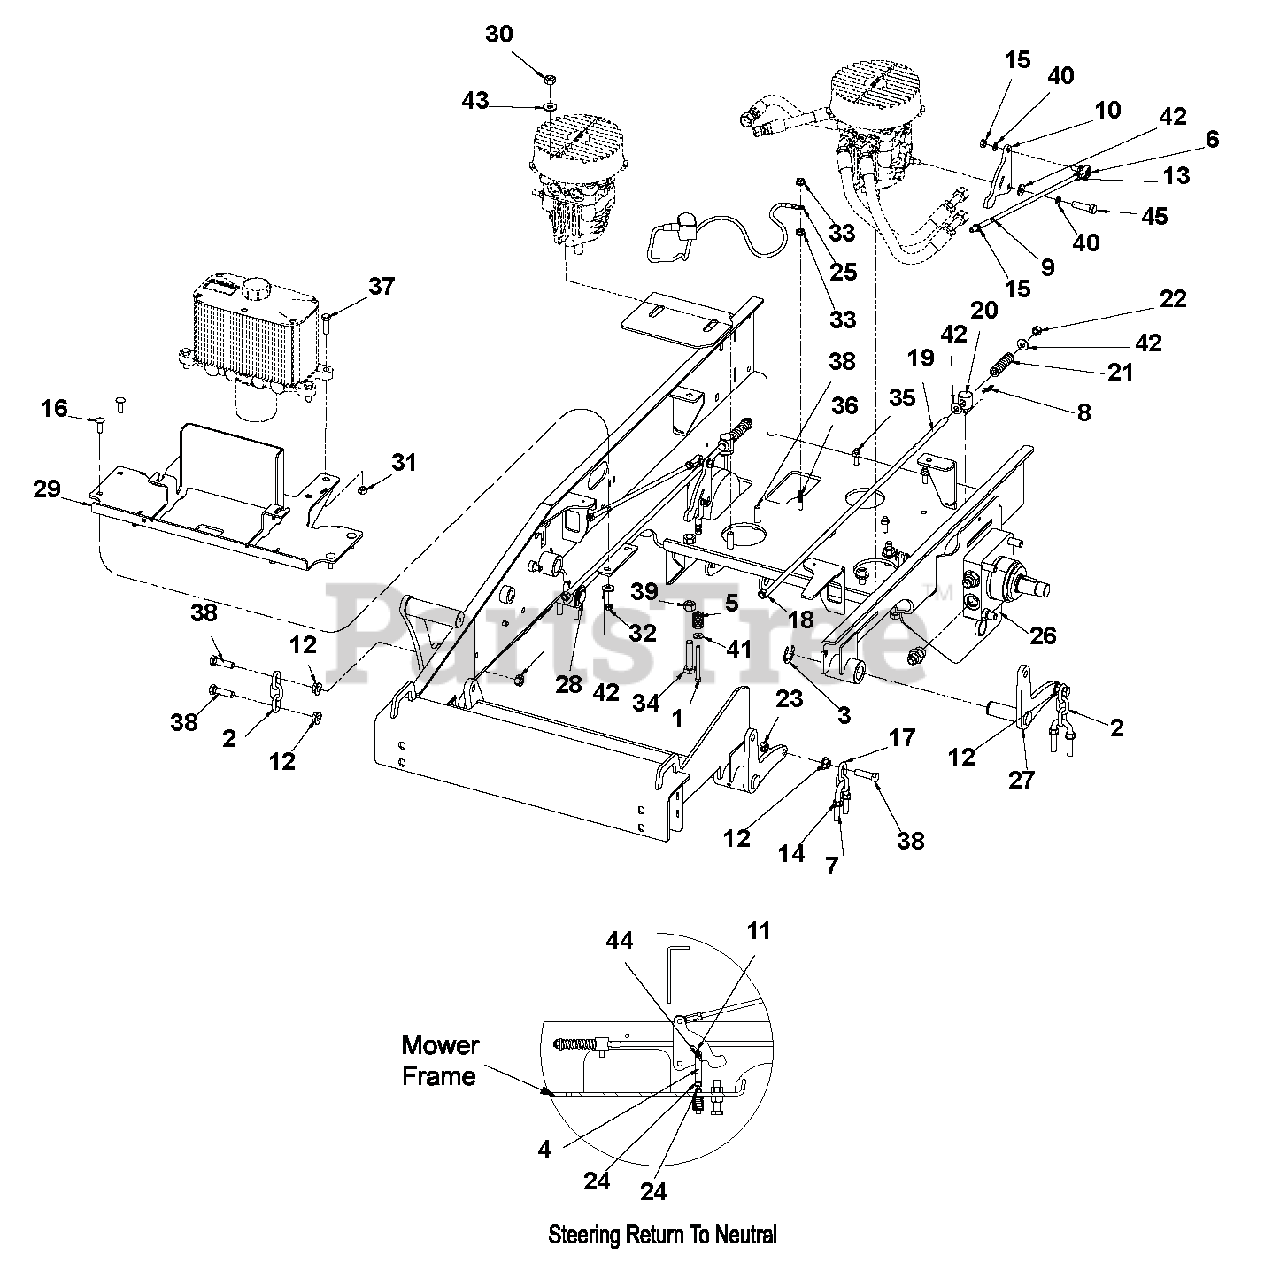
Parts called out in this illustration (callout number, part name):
1	BOLT, 1/4-20X2.75 SOC 8 Y
2	CHAIN, 1/4 X 3 LINKS Y
3	E-RING, 1.00 X .050 Y
4	YOKE, 1/4-20 RH ADJUSTABLE
5	SPRING, COM .784X.092X1.50
6	BALL JOINT, 5/16 FMAL W/STD
7	U-BOLT, RD 1.00X2.50X3/8-16 Y
8	RING, RUE .375 X .054 X 1.254
9	ROD, PUMP CONTROL HORNET
10	PLATE, PUMP CONTROL ARM
11	RING, RUE .250 X .041 X .844
12	LOCKNUT, 7/16-14 WHIZ Y
13	NUT, 5/16-24 HEX GR5 LH Y
14	NUT-SPIRALOCK-FLG .50-13 PLN
15	NUT-HEX .312-24 YWZC
16	@BLT-RDHDSQNK .31-18X1.00 G5YZ
17	CHAIN, 2 LINKS 1/4" Y
18	NUT, 3/8-24 STD HEX Y
19	ROD, BRAKE GEN 1
20	PIN, BRAKE LINKAGE
21	SPRING, COM .710X.142X2.50
22	LOCKNUT, 3/8-24 CROWN Y
23	LOCKNUT, 7/16-14 CENTER Y
24	@NUT-LK-NYL .250-20 YWZC
25	CABLE, BATTERY - 35" GROUND
26	WLDT, WHEEL MOTOR PLATE
27	WLDT, LH REAR DECK PIVOT
28	WLDT, RH REAR DECK PIVOT
29	WLDT, BATTERY/TANK (ARIENS)
30	LOCKNUT, 7/16-14 CROWN Y
31	LOCKNUT, 3/8-16 CROWN Y
32	LOCKNUT, 5/16-18 CROWN Y
33	LOCKNUT, 5/16-18 WHIZ Y
34	BOLT, 1/2-13X2.75 HEX 2 FLTD Y
35	@BLT-HEX .31-18X1.50 GR5 YWZC
36	@BLT-HEX .31-18X1.75 GR5 YWZC
37	BOLT, 3/8-16X1.25 HEX 5 Y
38	BOLT, 7/16-14X1.50 HEX 5 Y
39	NUT, 1/2-13 STD HEX GR5 Y
40	WASHER, .313 MED SPRG LOCK Y
41	WASHER, .250 REG FLAT Y
42	@WSHR-FL-STL.38X.875X.083 YWZC
43	@WSHR-FL-STL.438X1.00X.083 YWZ
44	PIN, CVS .250X1.00X.859 Y
45	BOLT, M8X1.25X20 HEX 8.8 Y
